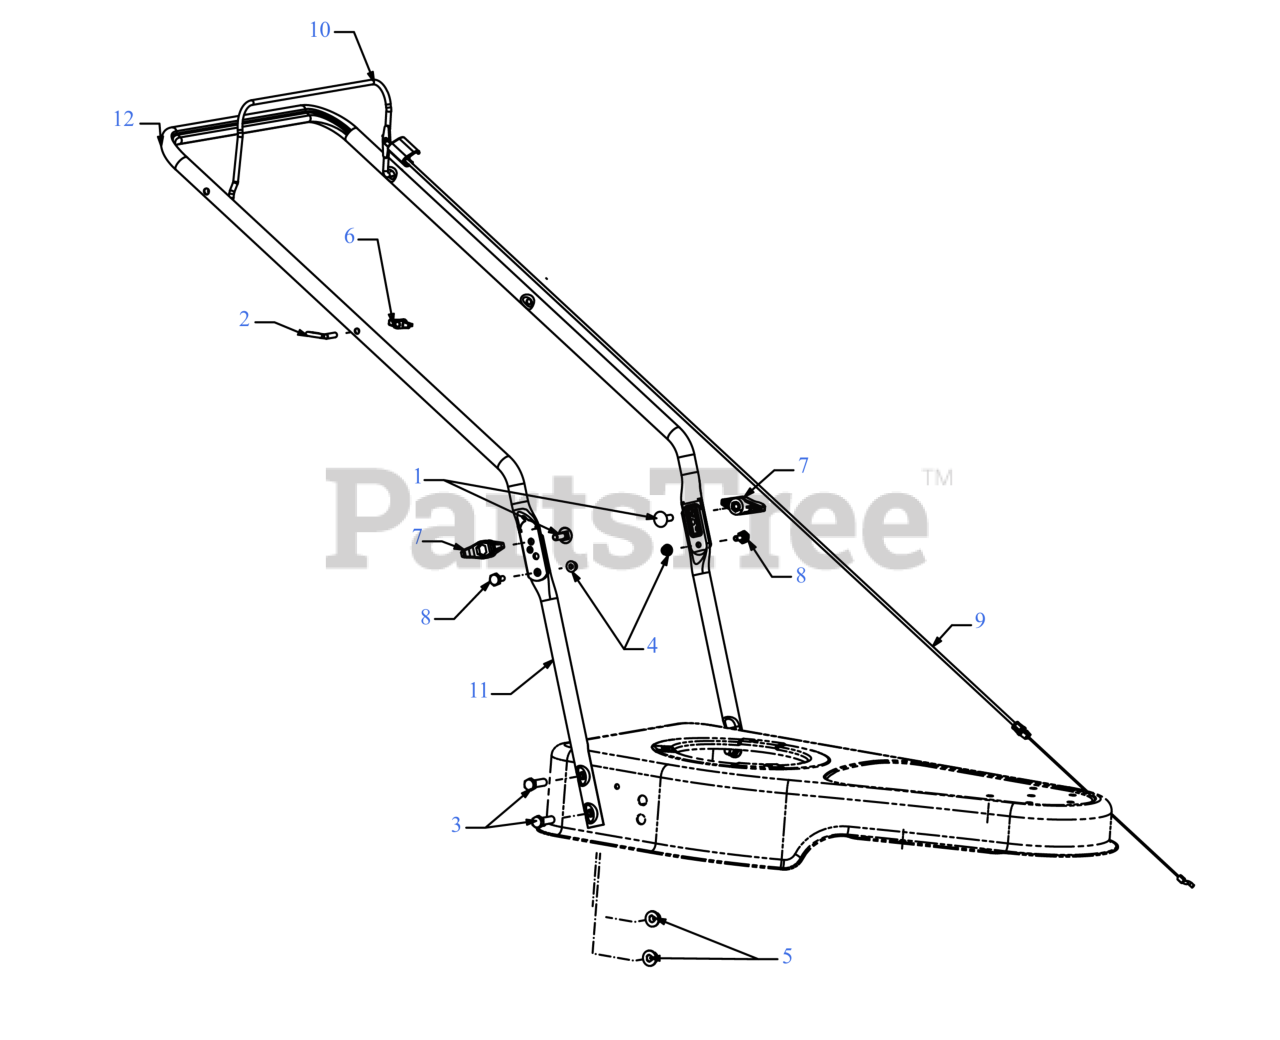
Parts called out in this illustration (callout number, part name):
1	SCREW 5/16-18 x 1.00 GR5
2	EYEBOLT 1/4-20
3	SCREW 3/8-16 x 1.25 GR5
4	FLANGE LOCK NUT
6	HANDLE KNOB
7	WING KNOB 5/16-18
8	SHOULDER SCREW
9	CONTROL CABLE 40"
